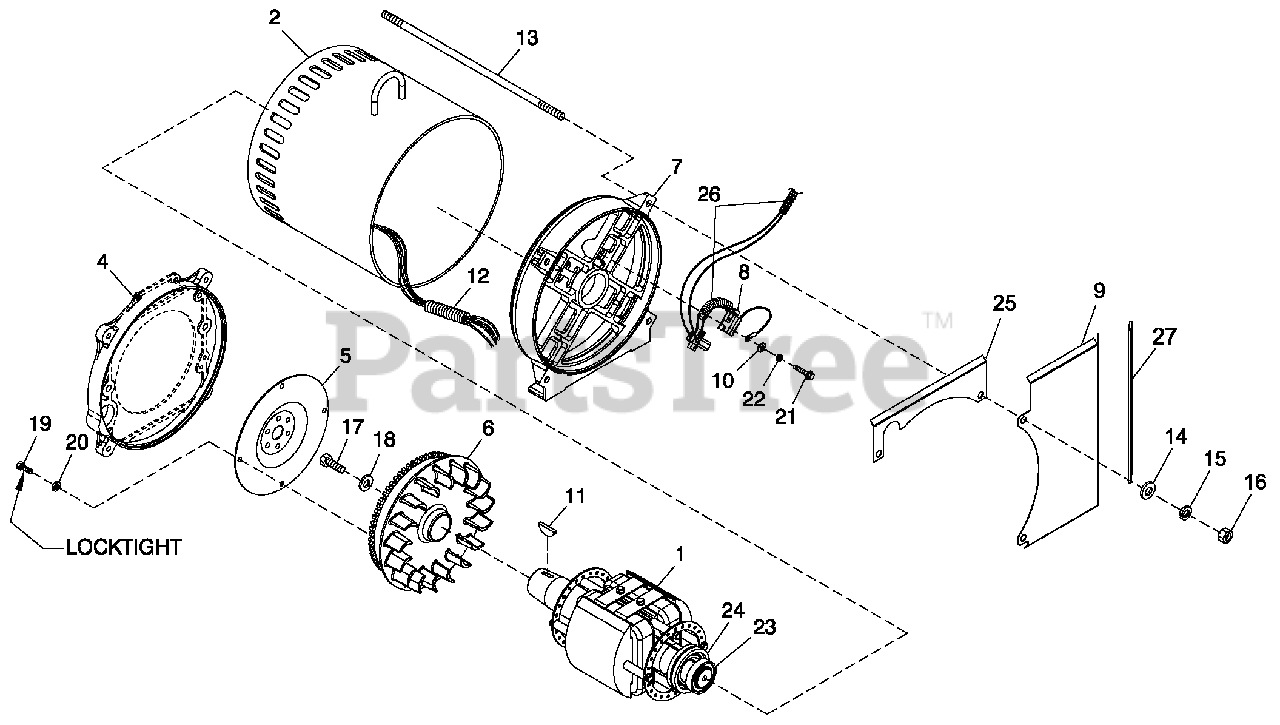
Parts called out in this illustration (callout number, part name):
1	R0T0R-2390-45KD1 CPL
2	STAT0R-390 45K 2P 1PH DIRECT
3	INSTR HYP0T TEST (N 0T SH0WN)
4	ENGINE ADAPTER
5	FLEXPLATE
6	ASSY FLYWHEEL CPL W/40MM FAN B
7	REAR BEARING CARRIER 390/DRCT
8	ASSY BRUSH H0LDER 390/HSB
9	GUARD REAR BEARING CARRIER
10	WASHER FLAT #8 ZINC
11	KEY W 00D R U FF #E
12	C0NDUIT FLEX 1.0" ID (35" LG)
13	STUD M 14-2.0 570 G5 ZINC
14	WASHER FLAT M14
15	WASHER L0C K M 14
16	NUT H E X M 14-2.0G 8Y E L CHR
17	SCREW H H C M 16-2.0X 45 G8.8
18	SPACER .69 X 2.75 X .37 ST/ZNC
19	SCREW HHC M10-1.50 X 16 G10.9
20	WASHER L0C K M 10
21	SCREW HHTT M4-0.7 X 16 BP
22	WASHER L0C K#8-M 4
23	BALL BEARING-45 MM
24	SLIP RING MACHINED
25	GUARD REAR BEARING CARRIER
26	C0NDUIT FLEX .38" ID (60")
27	TRIM VINYL BLACK 1/8GP (16.5"LG)
